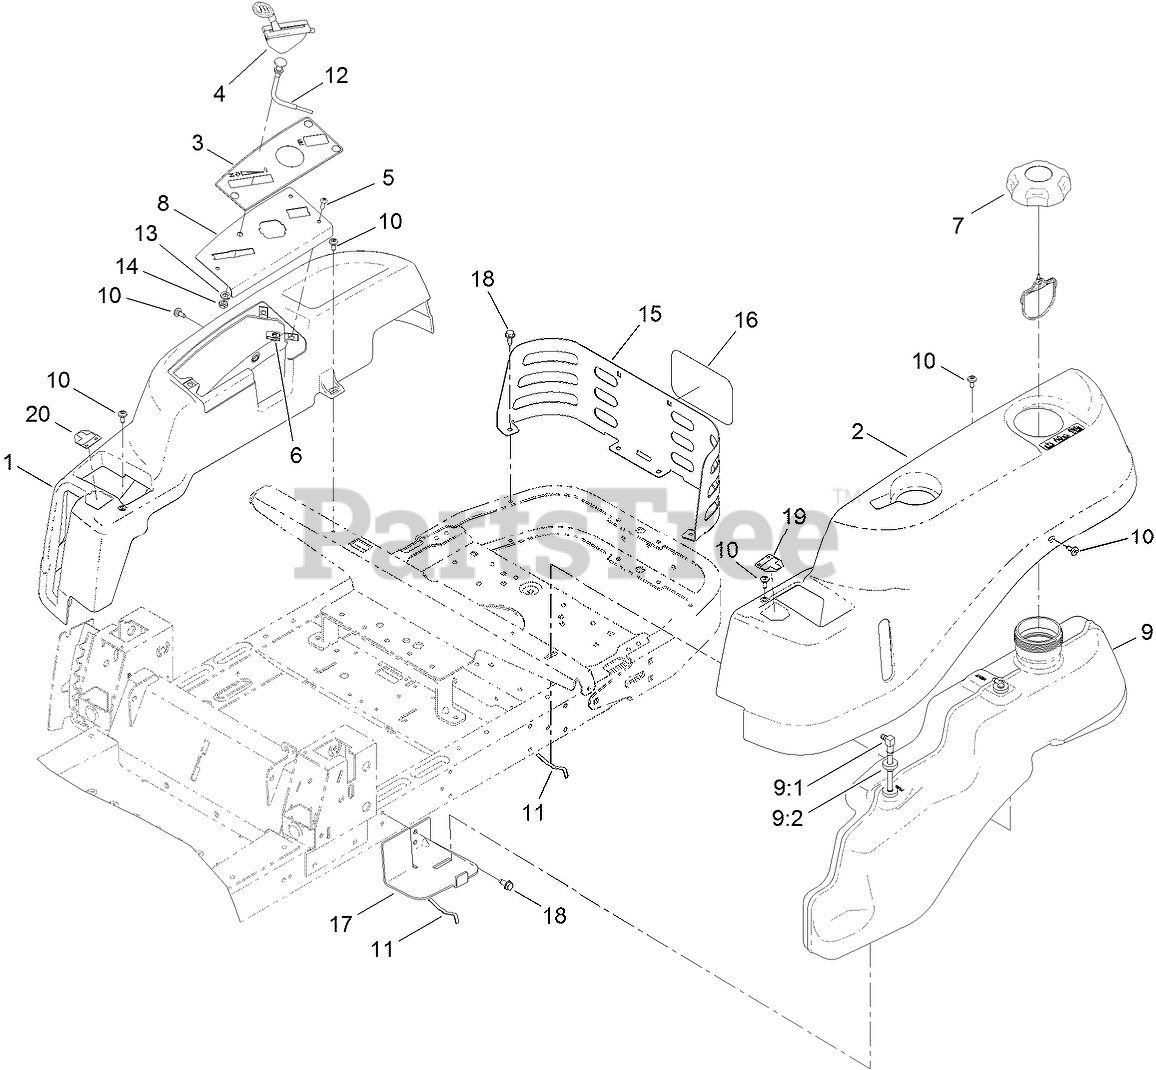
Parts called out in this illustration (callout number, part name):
1	POD-RH
2	POD-LH
3	DECAL-PANEL, CONTROL
4	CABLE-THROTTLE
5	SCREW-PRH
7	CAP-FUEL, RATCHETING
8	PLATE-CONTROL
9	FUEL TANK ASM
9:1	CONNECTOR-ELBOW, 90 DEG
9:2	BUSHING
10	SCREW-SHOULDER
11	SPRING
12	CABLE-CHOKE
13	WASHER-LOCK
14	NUT-HJ
15	GUARD-REAR
16	DECAL
17	SUPPORT-TANK, FRONT
18	SCREW-HWHTF
19	DECAL-CONTROL LEVER, LH
20	DECAL-CONTROL LEVER, RH
